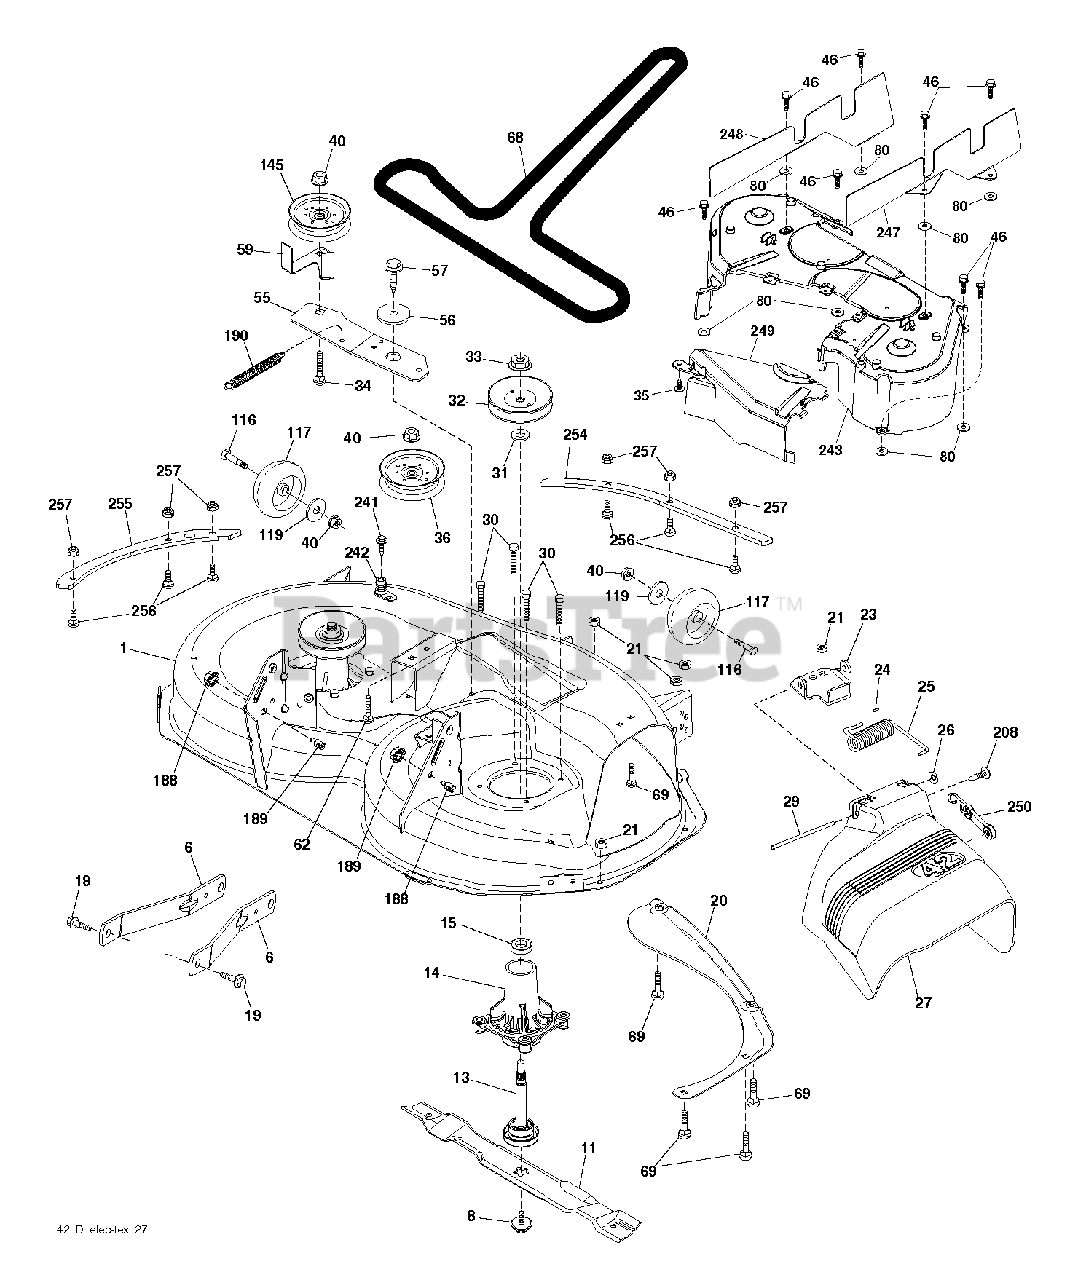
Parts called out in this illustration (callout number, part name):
1	DECK SVC 42"B 103 419175X498
6	ARM.SUSPENSION.MOWER.R
8	SCREW 7/16 X 20 X 1" HEX HEAD
11	42" HI-LIFT BLADE
13	RB MANDREL.ASM.SUB-NON.GR
14	HOUSING.MANDREL.REV.TALL.N/GRS
19	BOLT.SHOULDER
20	BAFFLE.VORTEX
21	LOCKNUT
23	BRKT.DEFLECTOR.38"2005+
24	CAP-SLEEVE LT
25	SPRING.TORSION.DEFLECT
26	NUT PUSH M
27	DEFLECTOR ASM.42"TEX.FRENCH
29	ROD.HINGE
30	SCREW, WASHER HEAD
31	WASHER.SPACER.MANDREL
32	PULLEY/MANDREL
33	NUT.FLANGE.LOCK.TOP
34	BOLT.3/8-16X1.50
35	FASTENER.XMAS.TREE
36	PULLEY.IDLER.2006
40	NUT LOCK FLG 3/8-16 UNC
46	SCREW.1/4-20X5/8
55	IDLER.ARM.42"
56	SPACER.RETAINER
57	SCREW 3/8-16X1
59	GUARD, BELT
68	BELT V SECONDARY
69	BOLT
80	PALNUT 1/4
116	BOLT M
117	WHEEL.GAGE.HALF.SPOKED
119	WASHER
145	PULLEY.IDLER.48"PRIMARY
188	STUD.FASTNER.W/ANTI-ROTATE
189	NUT LOCK HEX FLANGE 5/16-18
190	SPRING.MOWER.DRIVE.ELECTRIC
208	SCREW 3/8-16X1/2
241	SCREW.TT.#10-32X.5.3/8.FLANGE
242	PORT.WASHOUT
243	COVER DECK
247	SHIELD DECK RIGHT
248	SHIELD DECK LEFT
249	COVER CABLE CLUTCH
250	ELASTIC STRAP KIT
254	REINFORCEMENT.PLATE.42.FTX498
255	REINFORCEMENT PLATE 42 SD.X498
256	RHSNB, 1/4-20 X 1, GR5
257	NUT T
